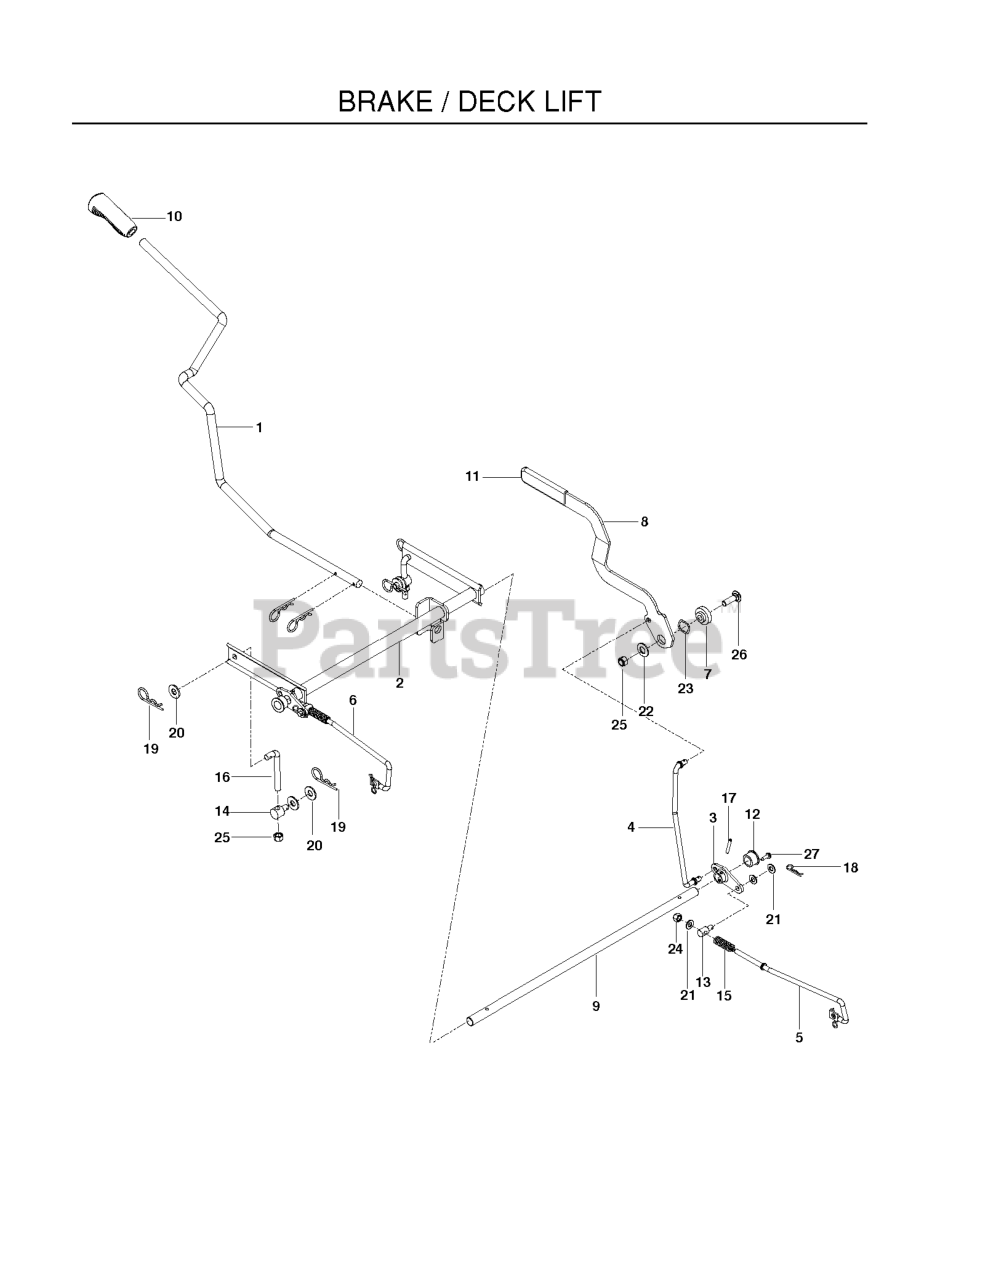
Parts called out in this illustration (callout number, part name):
1	ARM, LIFT HANDLE, BLK
2	SHAFT, LIFT WLDMT, BLACK
3	BELLCRANK, BRAKE
4	LINKAGE, BRAKE, UPPER
5	LINKAGE, EZT BRAKE RT
6	LINKAGE, EZT BRAKE LT
7	BRAKE ARM PIVOT
8	HANDLE, BRAKE, BLK
9	ROD, BRAKE
10	GRIP.LEVER.5625.ID
11	GRIP BRAKE HANDLE
12	PLASTIC BUSHING
13	BRAKE SWIVEL
16	L ROD 3-1/8"
17	ROLL PIN 3/16 X 1-1/4 ZD
18	HAIRPIN #2
19	HAIRPIN #4
20	WASHER 3/8 FLAT
21	FLAT WASHER 5/16 SAE
22	WASHER, 7/16 DISC SPRING
23	WASHER, .825 X 1.087, WAVE
24	NUT 5/16 NYLOC
25	NUT 3/8-16 NYLOC
26	RHSNB 3/8-16 X 1-1/4
27	SCREW #10 X 1/2 SELF TAPPING
